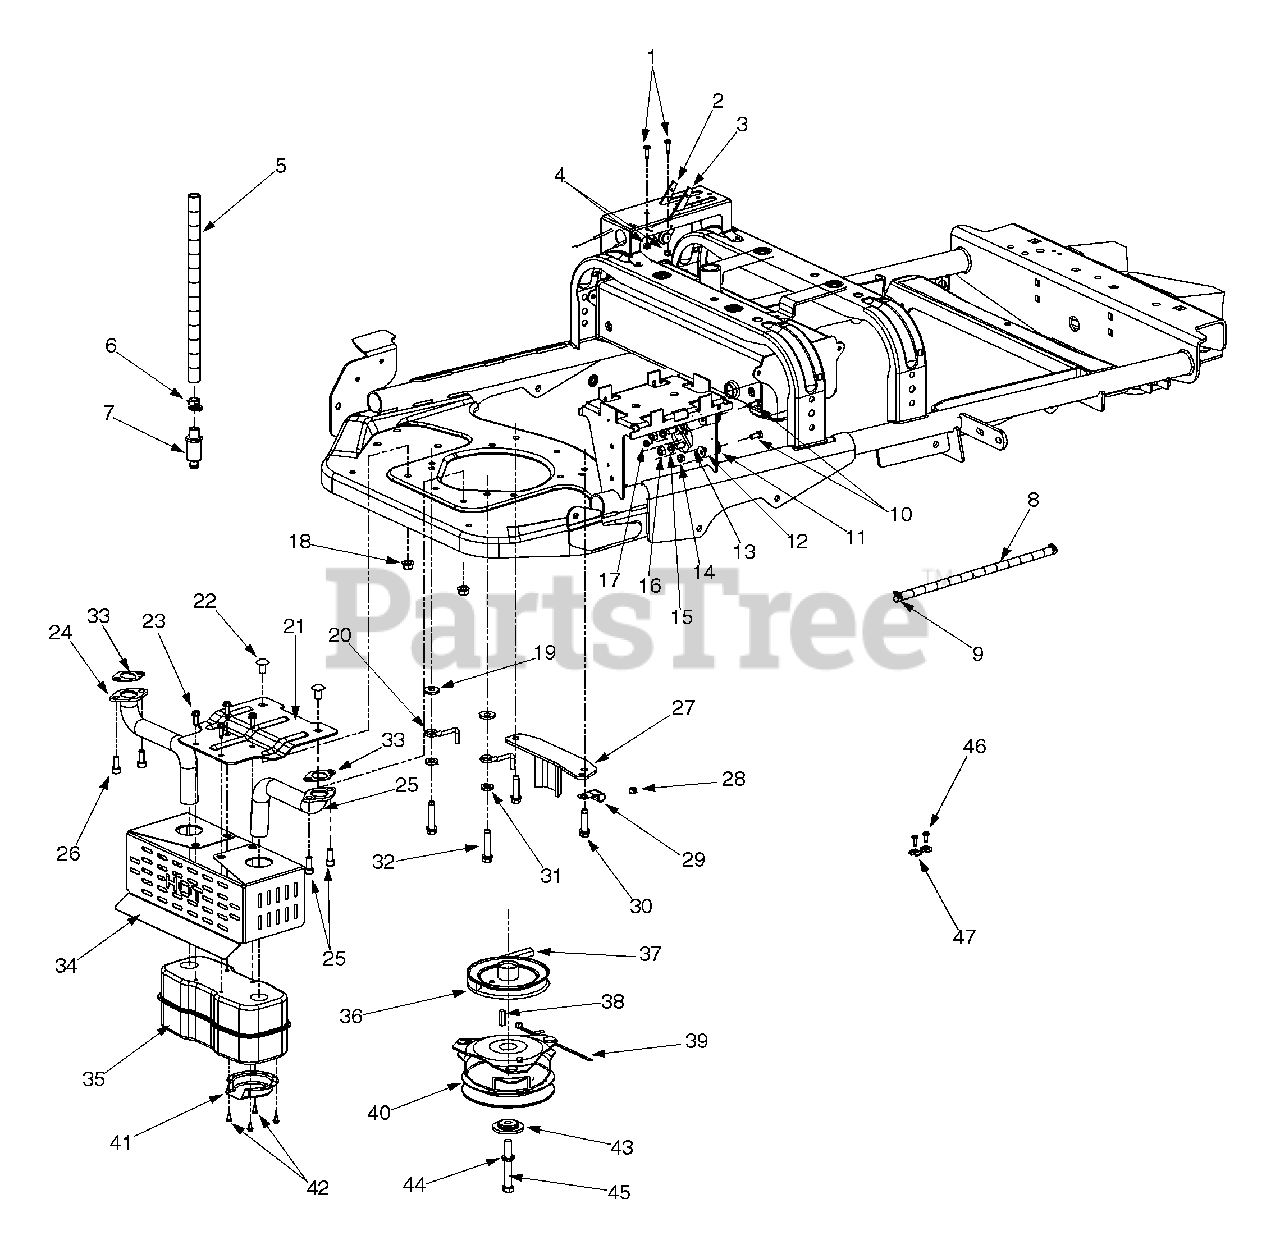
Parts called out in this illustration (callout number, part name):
1	Screw #10-24 x .750
2	Throttle Cable Control 40.5"
3	Choke Cable Control 52.0"
4	Nylon Lock Nut #10-24
5	Oil Drain Hose
6	Oil Drain Cap
7	Oil Drain
8	Fuel Line Hose
9	Hose Clamp
10	Hex Cap Screw 1/4-20 x .620
11	Lock Washer 1/4 ID x 3/4 OD
12	Bell Washer .265 ID x .75 OD
13	Solenoid Switch
14	Lock Nut 1/4-20
15	Lock Washer 5/16
16	Hex Nut 5/16-18
17	Hex Nut #10-32
18	Flange Lock Nut 3/8-16
19	Flat Washer .385 ID x 1.0 OD
20	Rear Belt Retainer Rod
21	Muffler Bracket
22	Carriage Bolt 3/8-16 x .75
23	Hex Washer Screw 1/4-20 x .750
24	Exhaust Pipe RH
25	Exhaust Pipe LH
29	Heat Shield Cable Clip
30	Hex Washer Screw 3/8-16 x 1.5
31	Flat Washer
32	Hex Washer Screw 3/8-16 x 1.875
33	Gasket
34	Muffler Guard
35	Muffler
36	Pulley
37	V-Belt
39	Cable Tie
40	Electric PTO Clutch
41	Muffler Deflector
42	Hex Washer Screw #8-32 x .375
43	Spacer Clutch
44	Lock Washer 7/16
45	Hex Cap Screw 7/16-20 x 3.25
46	Hex Washer Screw #10-32 x .625
47	Casing Clamp
